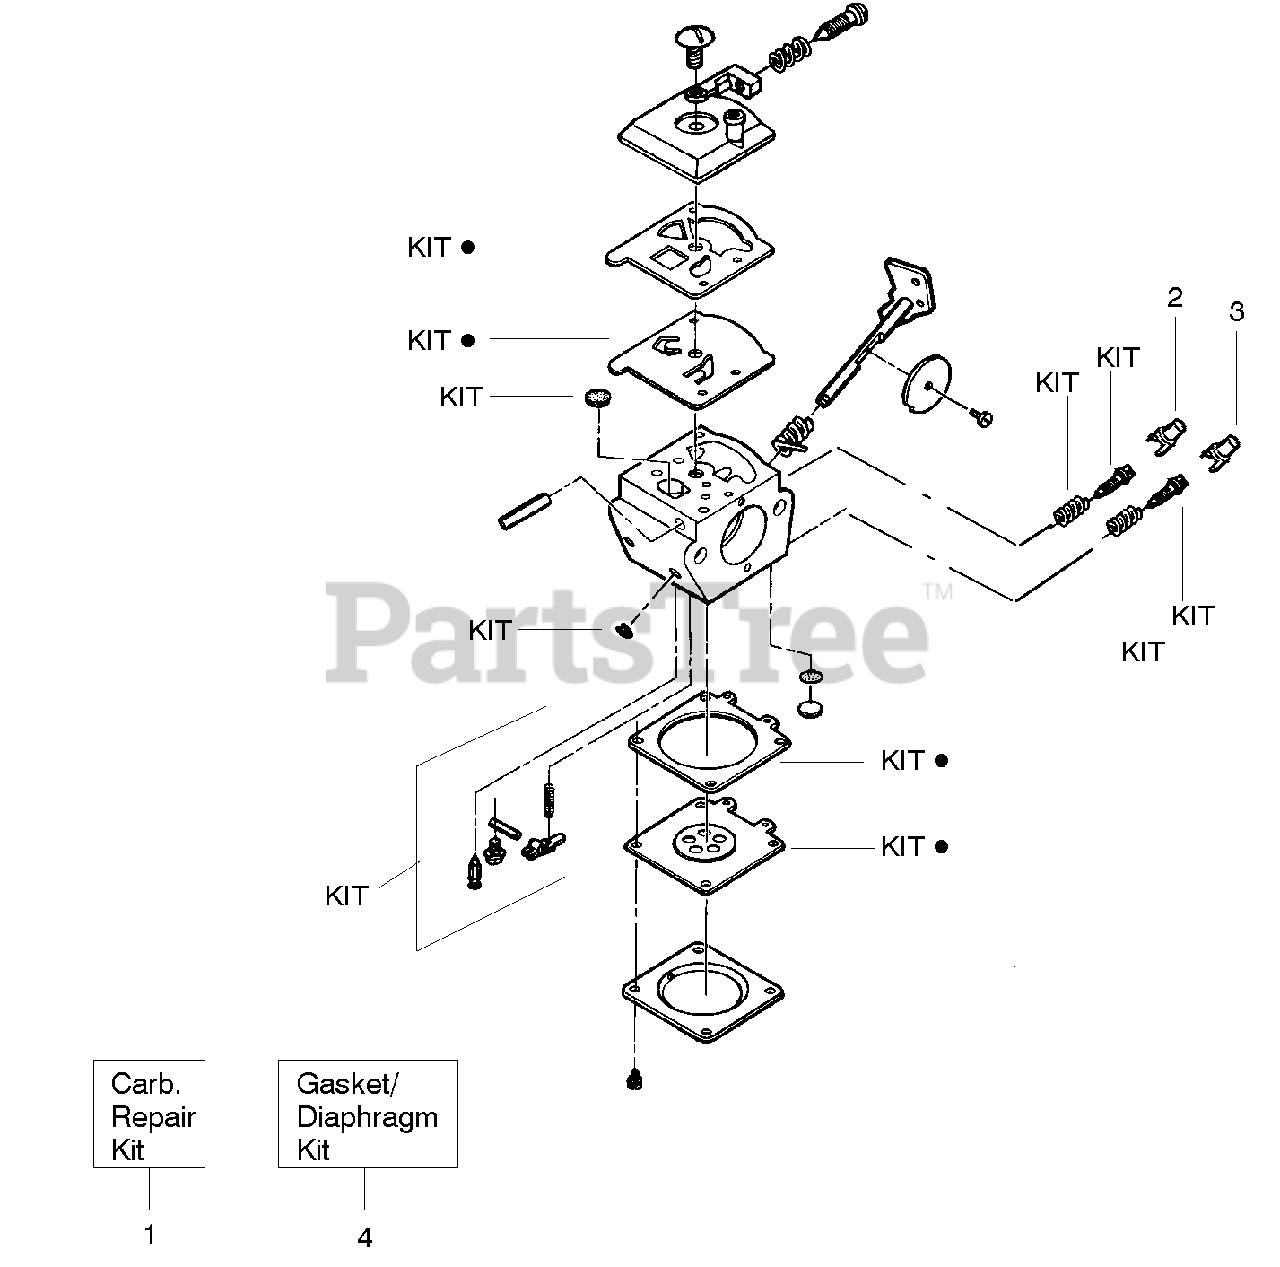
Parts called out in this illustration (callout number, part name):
1	Carburetor Repair Kit
2	Limiter Cap (High-brown)
3	Limiter Cap (Low-tan)
4	Gasket/Diaphragm Kit
